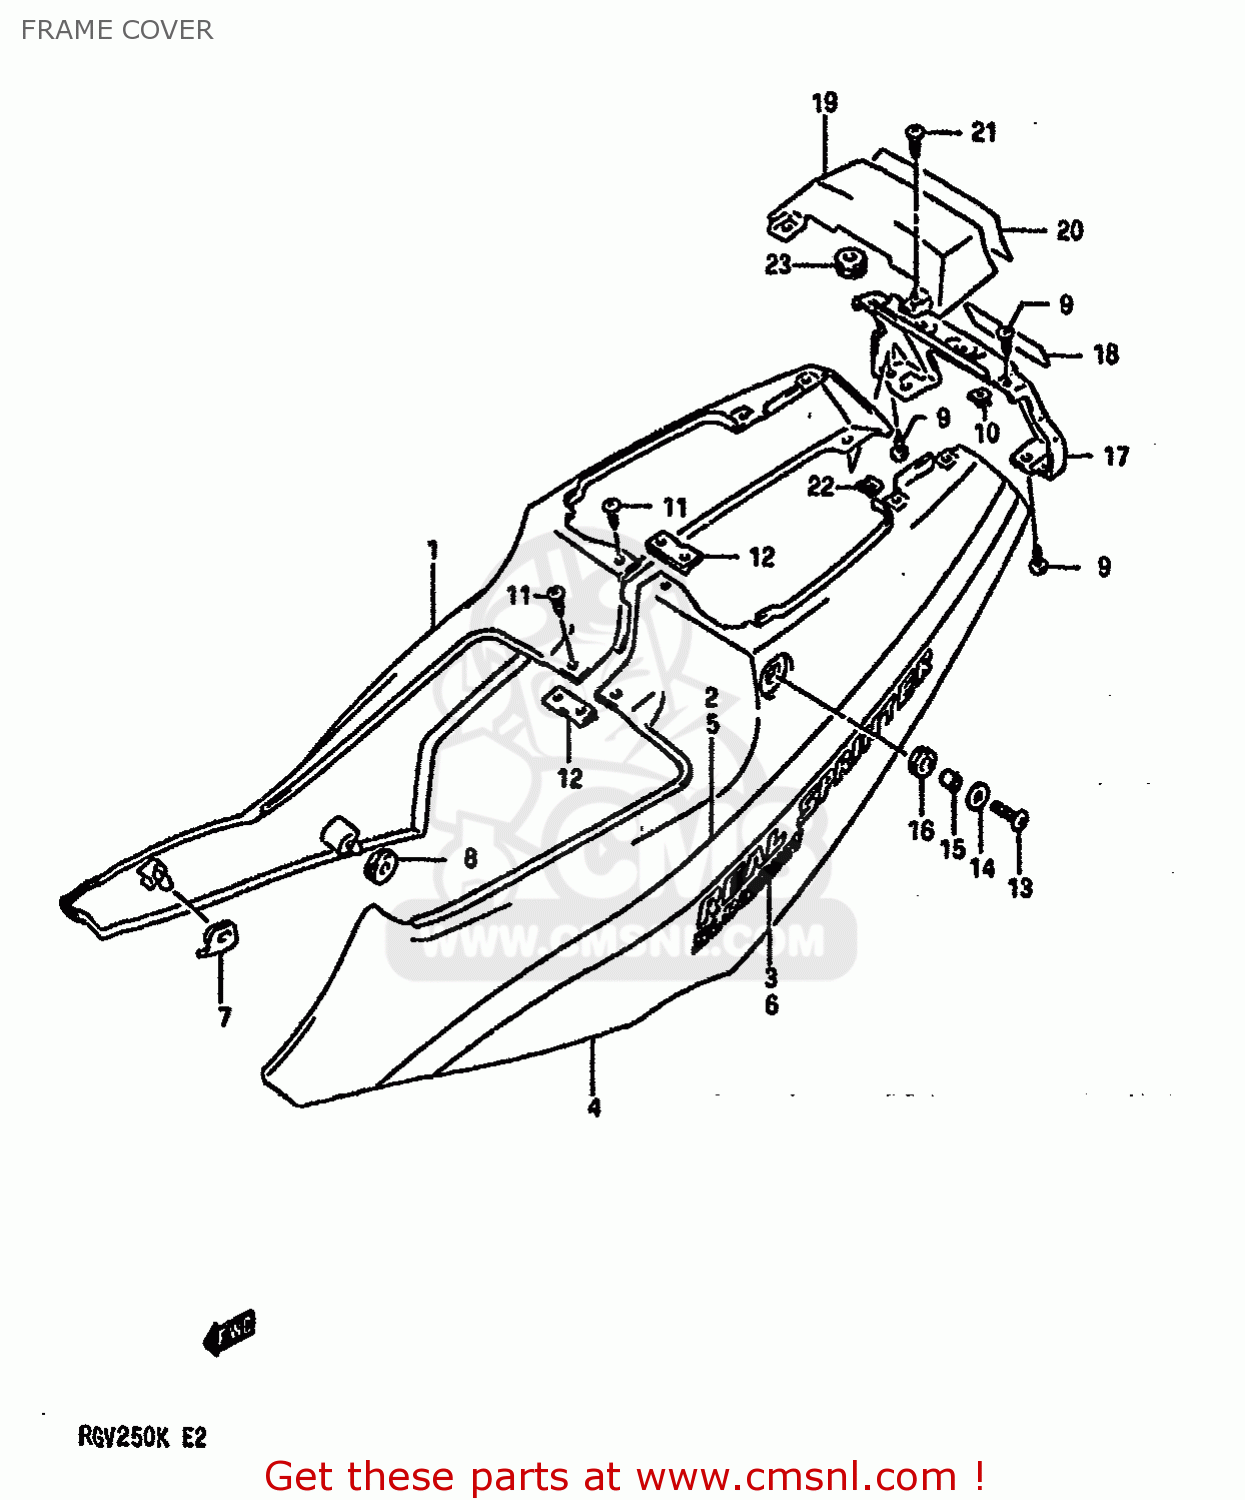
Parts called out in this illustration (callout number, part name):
1	COVER,FRAME RH (BLUE/BLUE)
2	TAPE SET,RH (WHITE)
3	EMBLEM,RH
4	COVER,FRAME LH (BLUE/BLUE)
5	TAPE SET,LH (WHITE)
6	EMBLEM,LH
7	CUSHION,FRAME COVER FR
8	CUSHION
9	SCREW 5X10
10	NUT
11	SCREW
12	NUT,FRAME COVER CTR
13	SCREW(6X20)
14	WASHER(6.5X22X1.6)
15	SPACER (6.1X8X8)
16	CUSHION
17	COVER,FRAME REAR (WHITE)
18	EMBLEM (BLUE)
19	COVER,FRAME REAR UPPER (BLUE)
20	TAPE (WHITE)
21	SCREW 5X10
22	NUT
23	CUSHION,COVER HEAD
